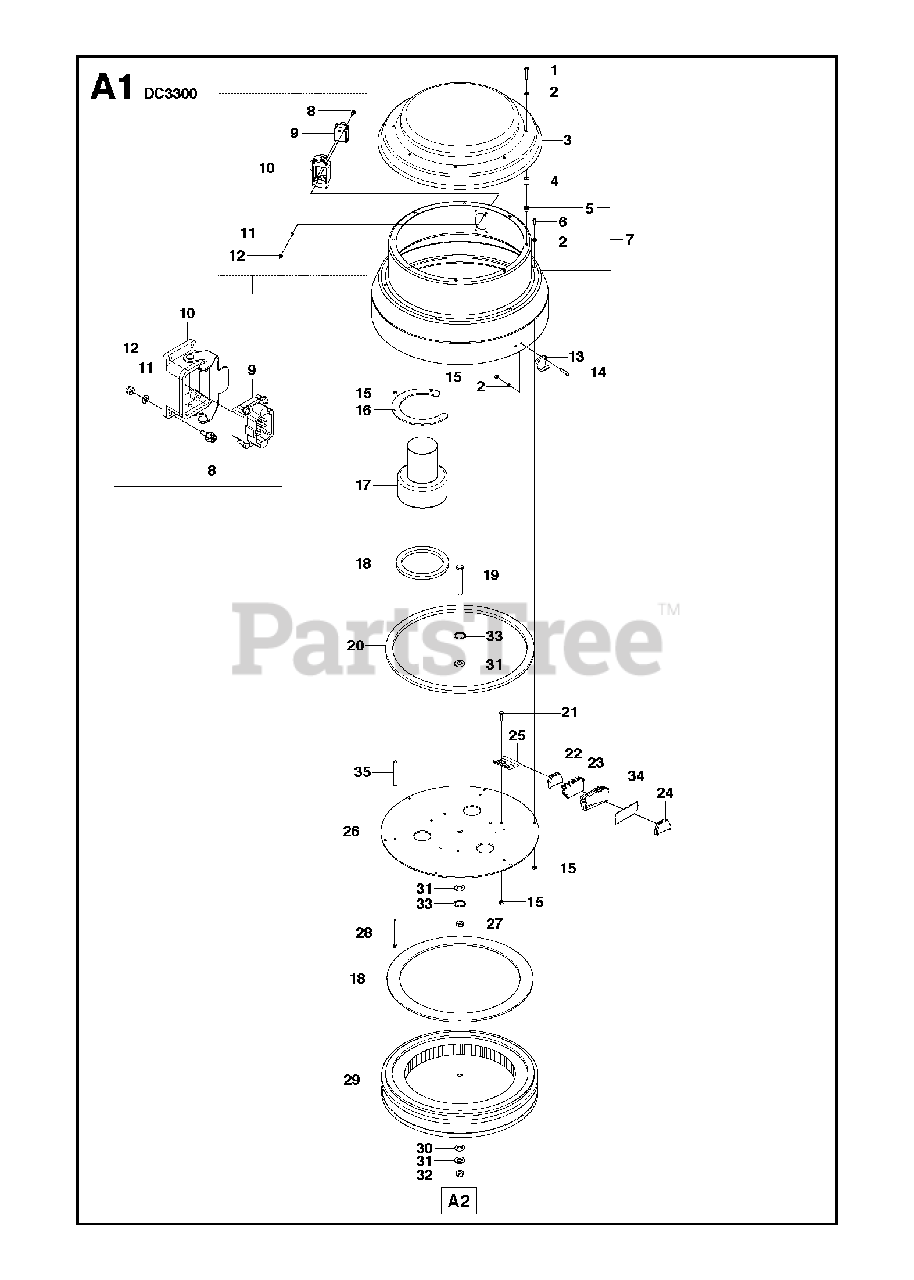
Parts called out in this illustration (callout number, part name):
8	SCREW CRPANM
12	HEXAGON LOCKING NUT
15	HEXAGON LOCKING NUT
